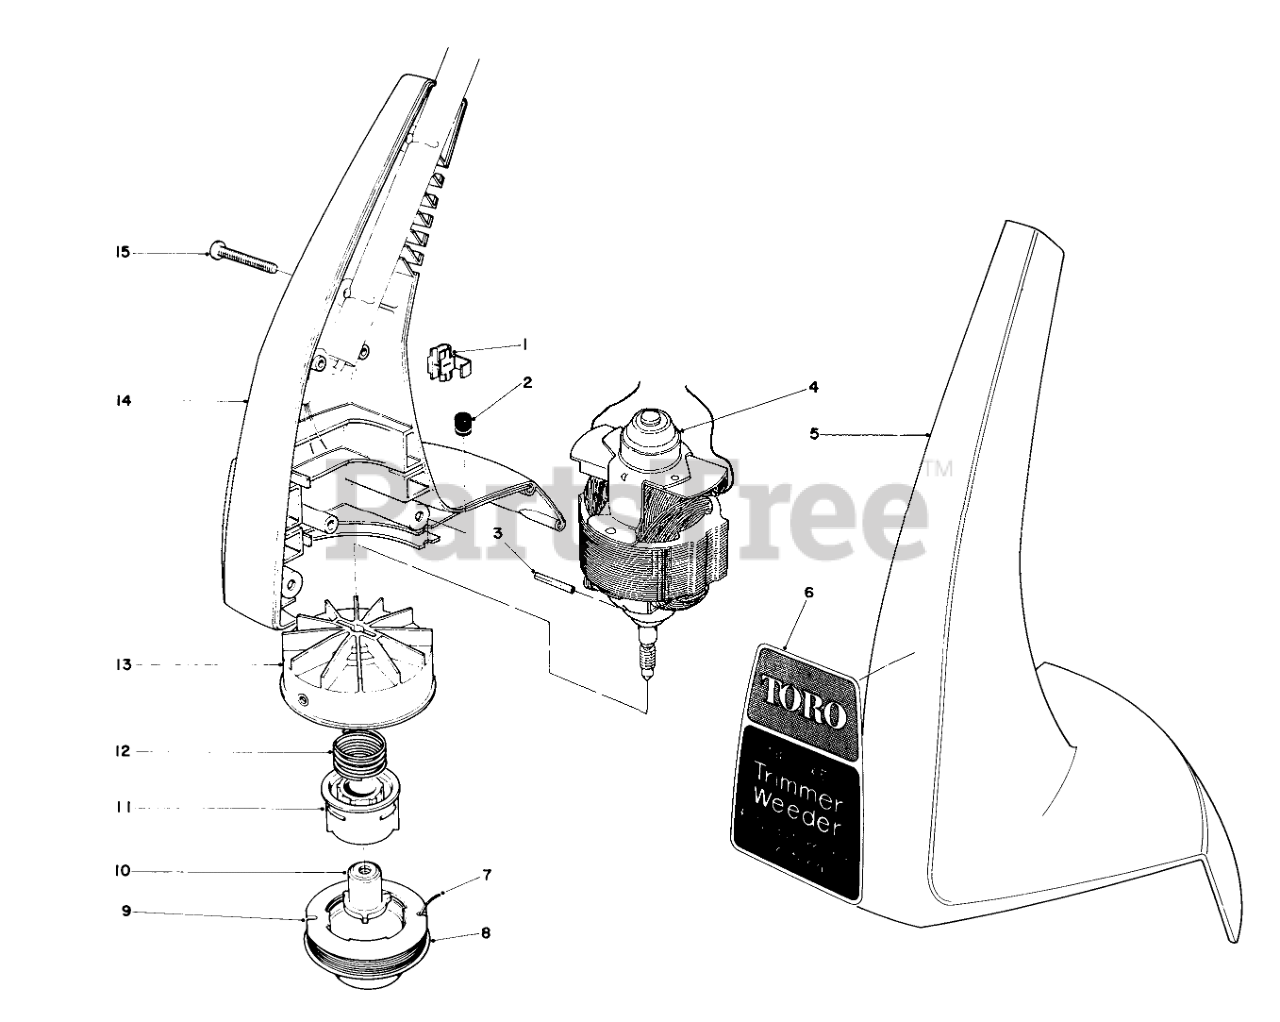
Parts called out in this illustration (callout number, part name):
1	CONNECTOR WIRE JOINT
2	GROMMET
3	COIL PIN
4	12 Volt D.C. Motor
5	Housing L.H.
6	Decal-Deluxe Trimmer
7	50-, .040" Dia.Cutting Line in Coil
8	Prewound Spool
9	SPOOL CAP
10	Driver
11	CORE - SPOOL
12	SPRING-COMPRESSION
13	FAN HUB ASM
14	Housing R.H.
15	Screw
